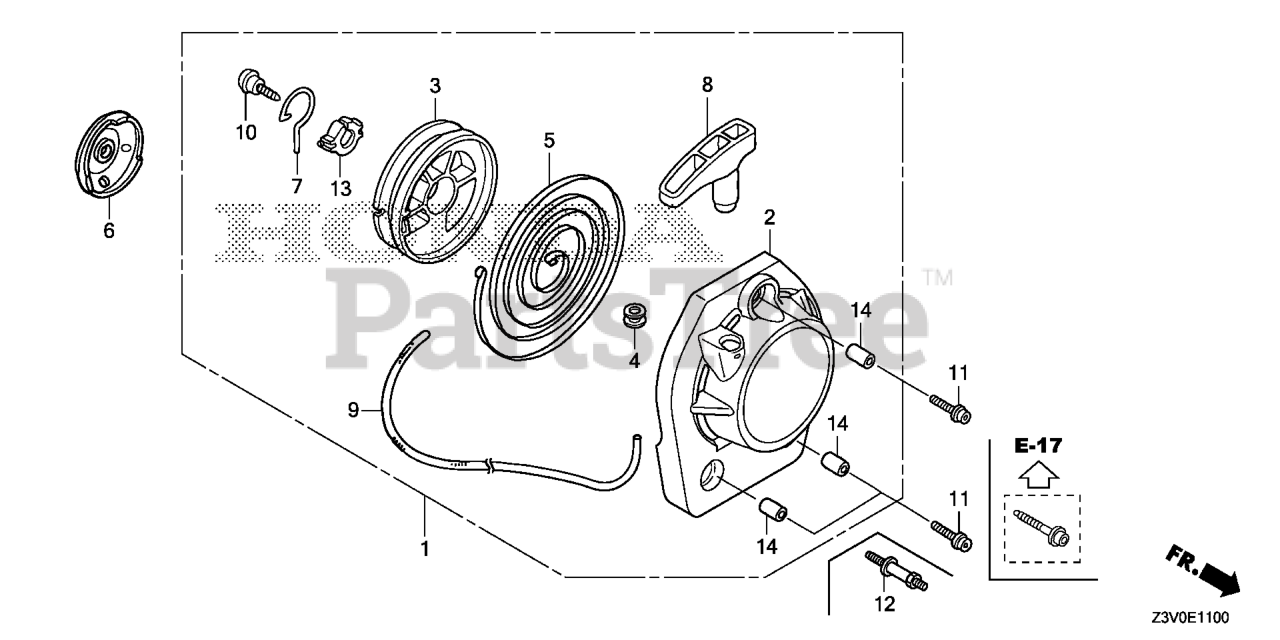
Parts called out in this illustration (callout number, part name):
1	STARTER ASSY., RECOIL
2	CASE, RECOIL STARTER
3	REEL, RECOIL STARTER
4	GUIDE, ROPE
5	SPRING, RECOIL STARTER
6	PULLEY, RECOIL STARTER
8	KNOB, RECOIL STARTER
9	ROPE, RECOIL STARTER (#3.5X40")
10	SCREW, SETTING
11	BOLT, SOCKET (5X16)
14	COLLAR A, HEAD COVER
